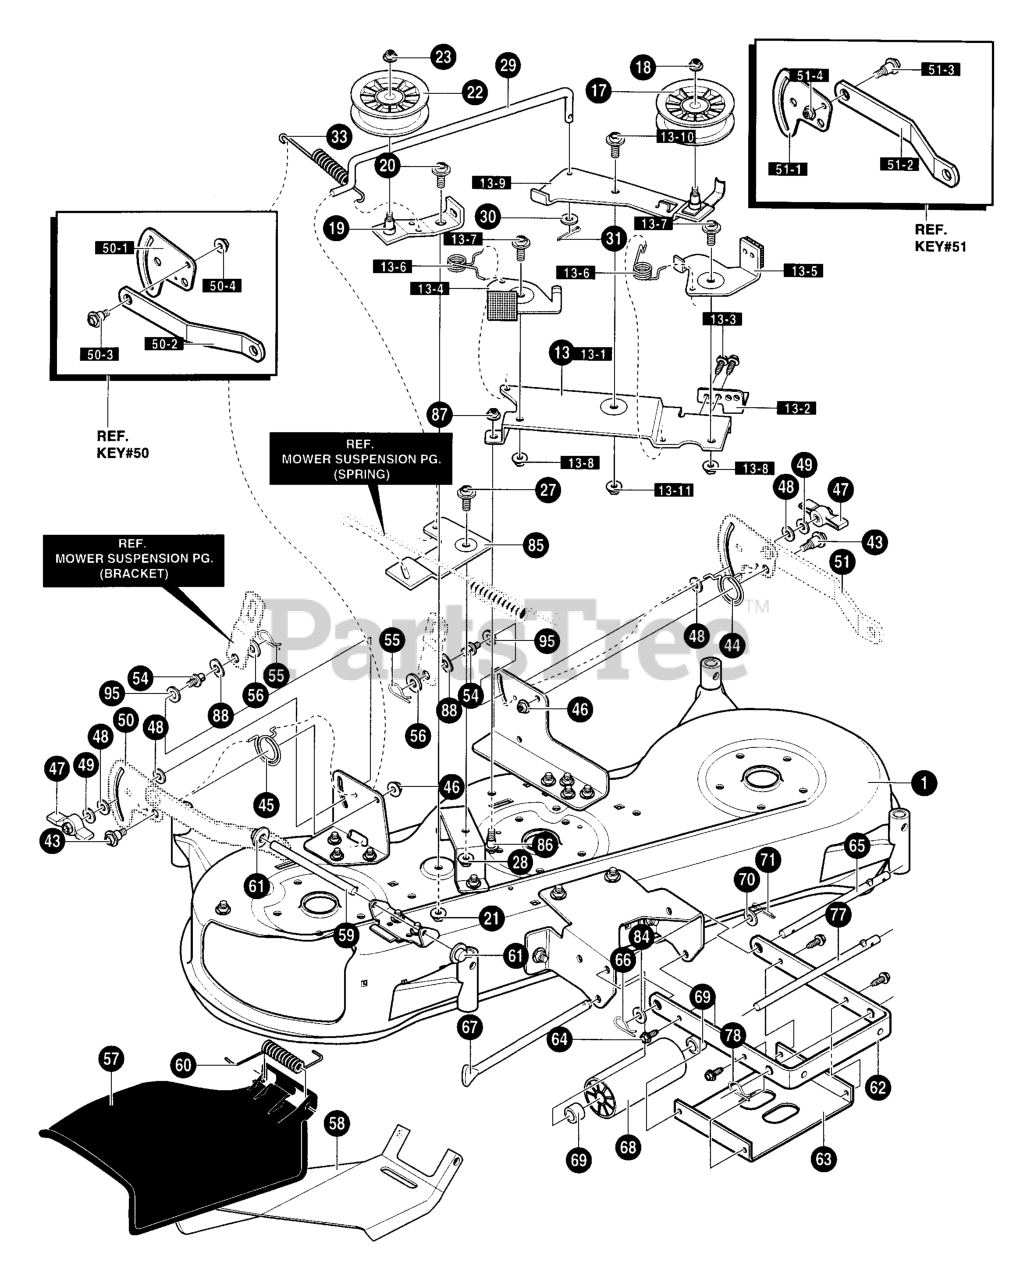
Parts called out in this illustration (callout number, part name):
1	MOWER DECK
13	BRAKE MOUNTING BRACKET
13-1	PLATE- BRAKE ARM MTG
13-2	BRACKET, BRAKE PLATE
13-3	SCREW 5/16-18X.75
13-4	ASSY, BRAKE RH
13-5	ASSY, BRAKE RH
13-6	TORSION SPRING
13-7	BOLT, 3/8-16
13-8	NUT, 3/8-16
13-9	IDLER ASSEMBLY
13-10	BOLT 3/8-16
13-11	NUT 3/8-16
17	PULLEY, IDLER
18	NUT, 3/8-16
19	ASSY, IDLER ARM RH 46"
21	NUT
22	PULLEY, IDLER
23	NUT
28	NUT 3/8-16
29	LINK, BELLCRANK
30	Washer
31	PIN, COTTER
33	SPRING, EXT
43	BOLT, SHOULDER
44	SPRING, TORSION LH
45	SPRING, TORSION RH
46	NUT
47	WINGNUT 5/16-18
48	PAD, FRICTION
50	PLATE, REAR SUS. BRKT RH
50-1	PLATE, SUSPENSION
50-2	SUSPENSION BRKT REAR
50-3	BOLT, SHOULDER
50-4	NUT
51	PLATE, REAR SUS. BRKT. LH
51-1	PLATE - SUSPENSION
51-2	SUSPENSION BRKT REAR
51-3	BOLT, SHOULDER
51-4	NUT
54	PIN, HANGER
55	HAIRPIN
56	FLATWASHER
57	DEFLECTORS, 46" DECK CHUTE
58	DEFLECTORS, INNER CHUTE 46"
59	ROD, DEFLECTOR
60	SPRING, TORS.
61	NUT, PUSH CAP
62	BRACKET, FRONT SUSPENSION
63	STIFFENER, FRONT HANGER
65	ROD, DECK
66	HAIRPIN
67	ZINC ROD, ROLLER
68	ROLLER, 6" NOSE 46" DECK
70	WASHER, FLAT
71	PIN, HAIR
77	ROD, HANGER
78	PIN, HAIR
84	WASHER, FLAT
85	BELLCRANK 46"
86	BOLT, 5/16-18X.63
87	NUT, 5/16-18
88	WASHER, WAVE
